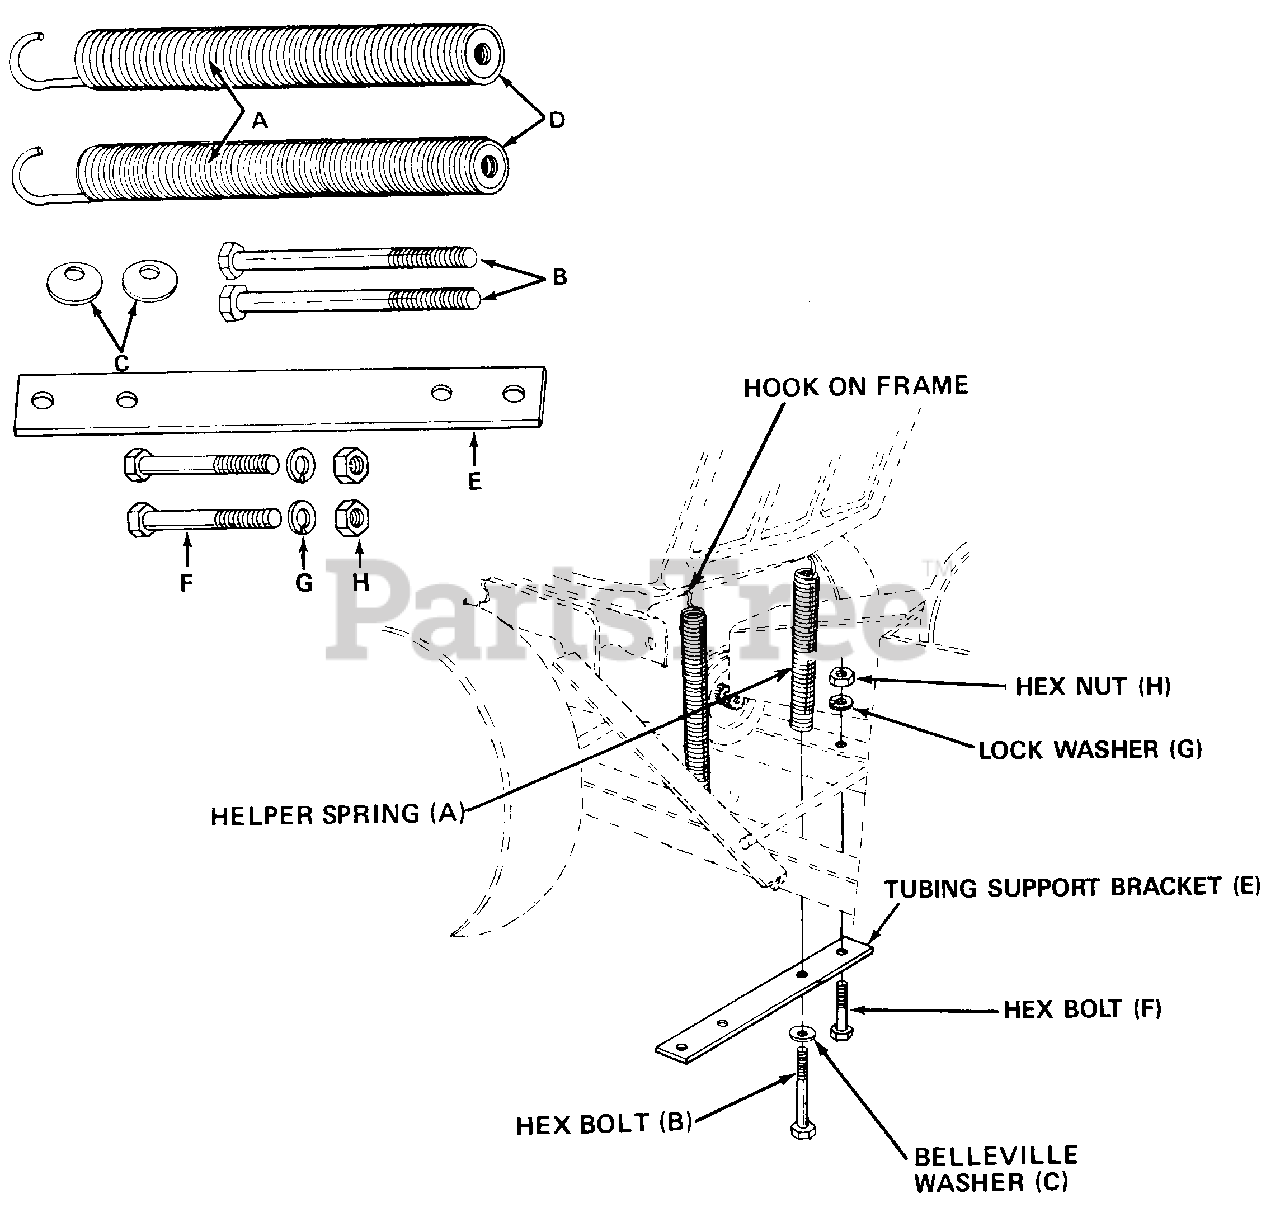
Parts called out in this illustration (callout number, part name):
A	Helper Springs
B	Hex Bolts
C	Belleville Washers
D	Spring Inserts
E	Tubing Support Bracket
F	Hex Bolts
G	Lock Washer
